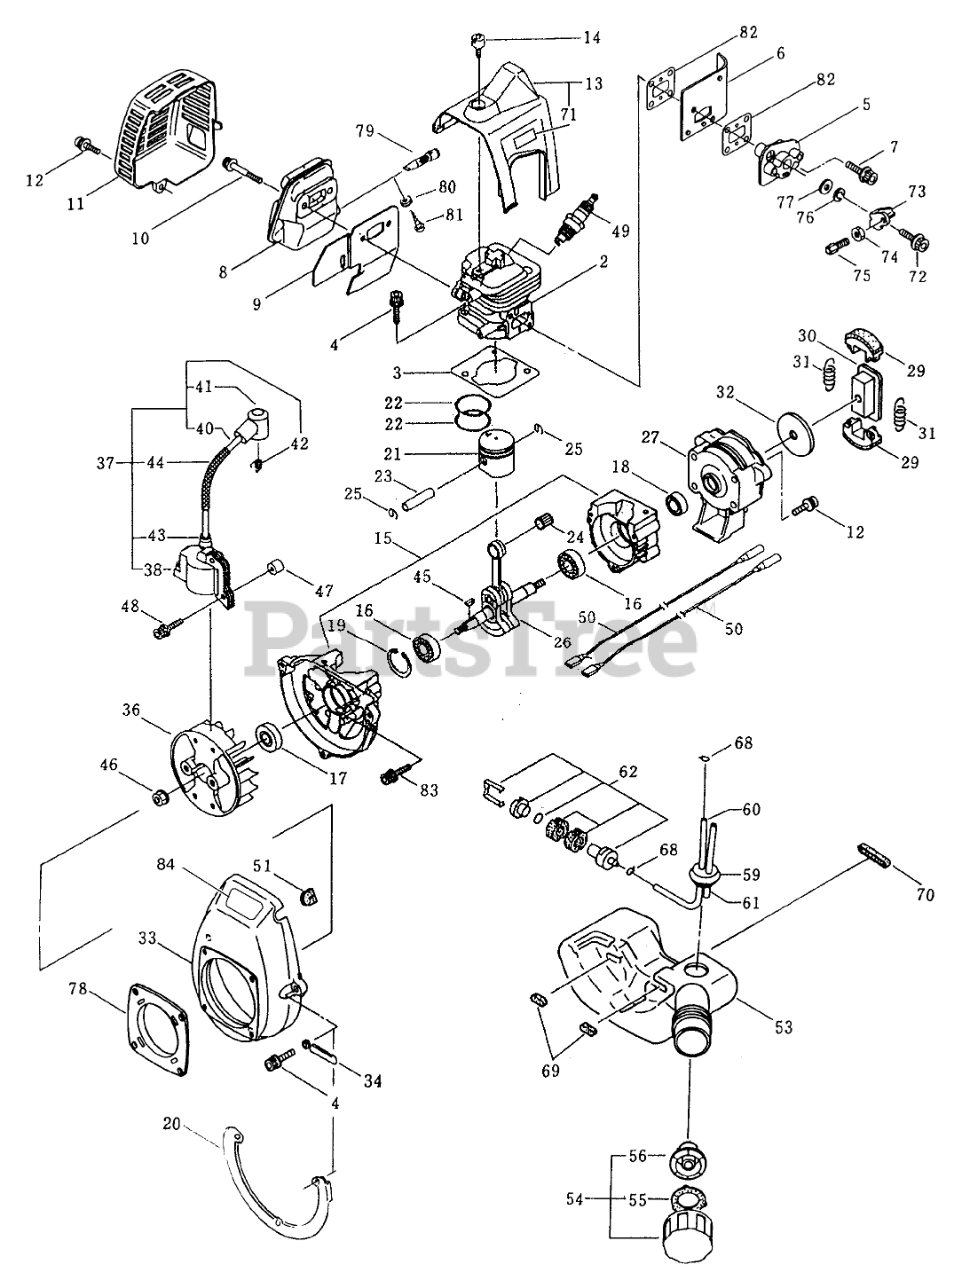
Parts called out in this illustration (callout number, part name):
2	Cylinder
3	GASKET
5	INSULATOR
6	DUCT - AIR
7	SCREW
8	MUFFLER
9	GASKET
10	CAPSCREW
11	COVER - MUFFLER
13	COVER - CYLINDER
14	COVER - KNOB,TOP
15	CRANKCASE
16	BEARING
17	SEAL - OIL
18	SEAL - OIL
19	RING - SNAP
20	PLATE
21	PISTON
22	RING - PISTON
23	PIN - PISTON
24	BEARING - NEEDLE
25	CIRCLIP
26	CRANKSHAFT
27	CASE - CLUTCH
29	SHOE - CLUTCH
30	BOSS - CLUTCH
31	SPRING
32	WASHER
33	COVER - FAN
34	CLAMP
36	FAN - ROTOR
37	Ignition Coil Assembly (Incl. Ref. #38-44)
40	CABLE - IGNITION
41	CAP - PLUG
42	CONNECTOR
45	KEY - WOODRUFF
47	SPACER
49	SPARK PLUG
51	GROMMET
53	TANK - FUEL
54	Tank Cap Assembly (Incl. Ref. #55-56)
55	GASKET
56	ASM - BREATHER
59	GROMMET
60	PIPE - FUEL
61	PIPE - RETURN
62	ASM - FUEL FILTER
71	DECAL - WARNING
72	CAPSCREW
75	ADAPTER
76	WASHER
77	WASHER
78	PLATE
79	ARRESTER - SPARK
80	WASHER
81	SCREW
82	GASKET
83	CAPSCREW
84	Decal-Toro
